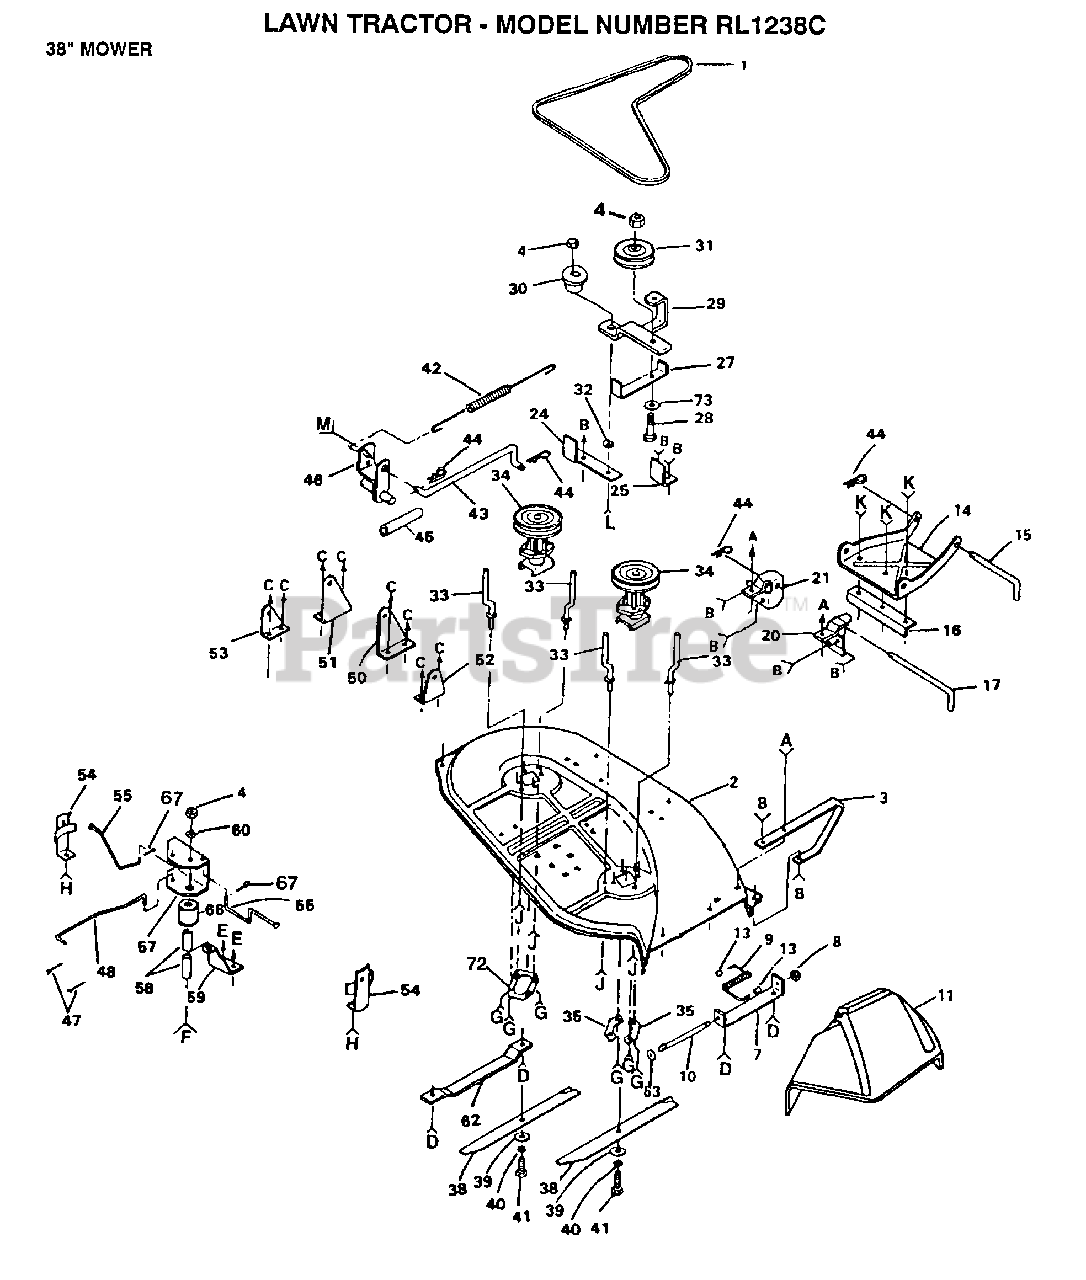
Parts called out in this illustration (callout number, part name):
1	BELT-V.79.1.MWR
5	WASHER M
6	BOLT
8	NUT PUSH M
10	ROD-HINGE T
11	DEFLECTOR-SHLD T
13	CAP-SLEEVE LT
14	LINK.PARALLEL
15	"ROD, FRT. PARAL T"
16	LINK STOP
17	HINGE PIN T
20	BRACKET RH LT
21	BRACKET LH T
22	BOLT
24	SUPPORT ARM T
25	STOP T
30	SPACER RETAINER
32	"WASHER, WEAR LT"
33	BELT KEEPER LT
35	SUPPORT PLATE LT
36	SCREW
37	SCREW
38	"BLADE.38""LOW LIFT"
39	WASHER
41	BOLT.3/8-24X1-1/2
44	SPRING.RETAINER
45	SPACER T
48	ROD BRAKE LT
49	BOLT
52	"BRKT,SUSP RH T"
53	"BRKT,SUSP REAR LH"
54	BRAKE LT
55	"ROD, BRAKE LH LT"
56	ROD BRAKE LT
57	"BRK,BRAKE,PVT LT"
58	SPACER BRAKE LTV
59	BRACKET SUPT LTV
60	WASHER
61	BOLT
62	RUNNER-LH M
63	WASHER
64	BOLT.3/8-14X1.25
69	BOLT LT
70	WASHER T
72	SUPPORT T
73	WASHER
